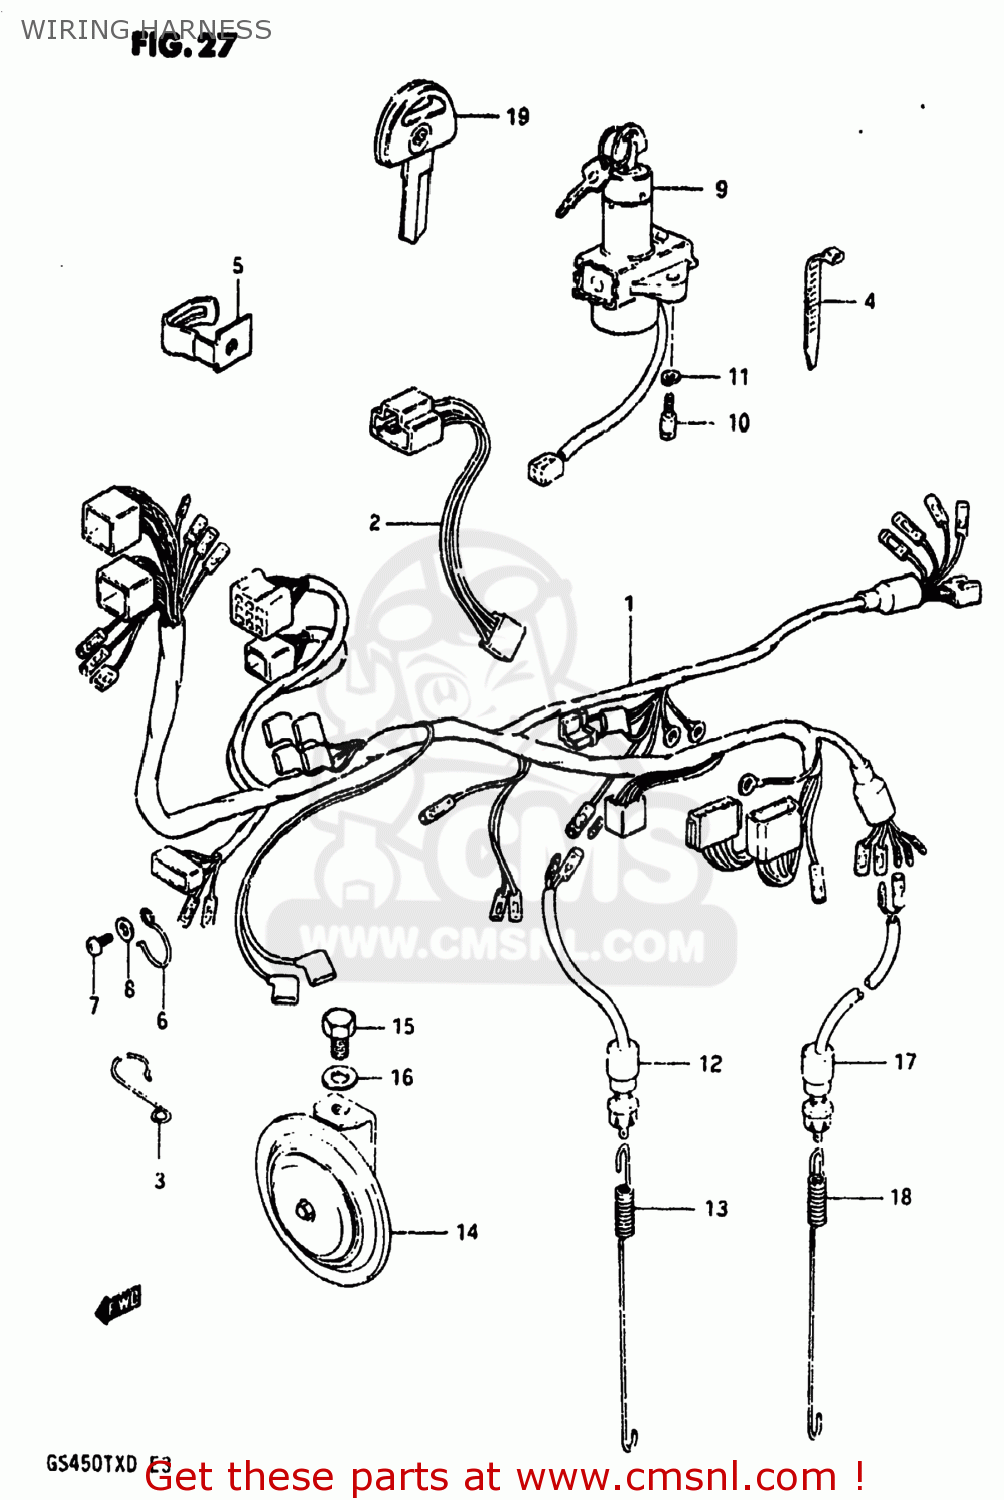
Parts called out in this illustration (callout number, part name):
1	HARNESS,WIRING
2	LEAD WIRE,HEADLAMP
3	CLIP,WIRING HARNESS
4	CLAMP(L:125)
5	CLAMP,WIRING HARNESS
6	GUIDE,WIRING HARNESS
7	SCREW 6X12
8	WASHER
9	SWITCH ASSY,IGNITION
10	BOLT
11	LOCK WASHER
12	SWITCH ASSEMBLY,STOP LAMP
13	SPRING
14	HORN ASSEMBLY
15	BOLT 8X12
16	WASHER
17	SWITCH ASSEMBLY,SIDE STAND
18	SPRING
19	KEY,BLANK
